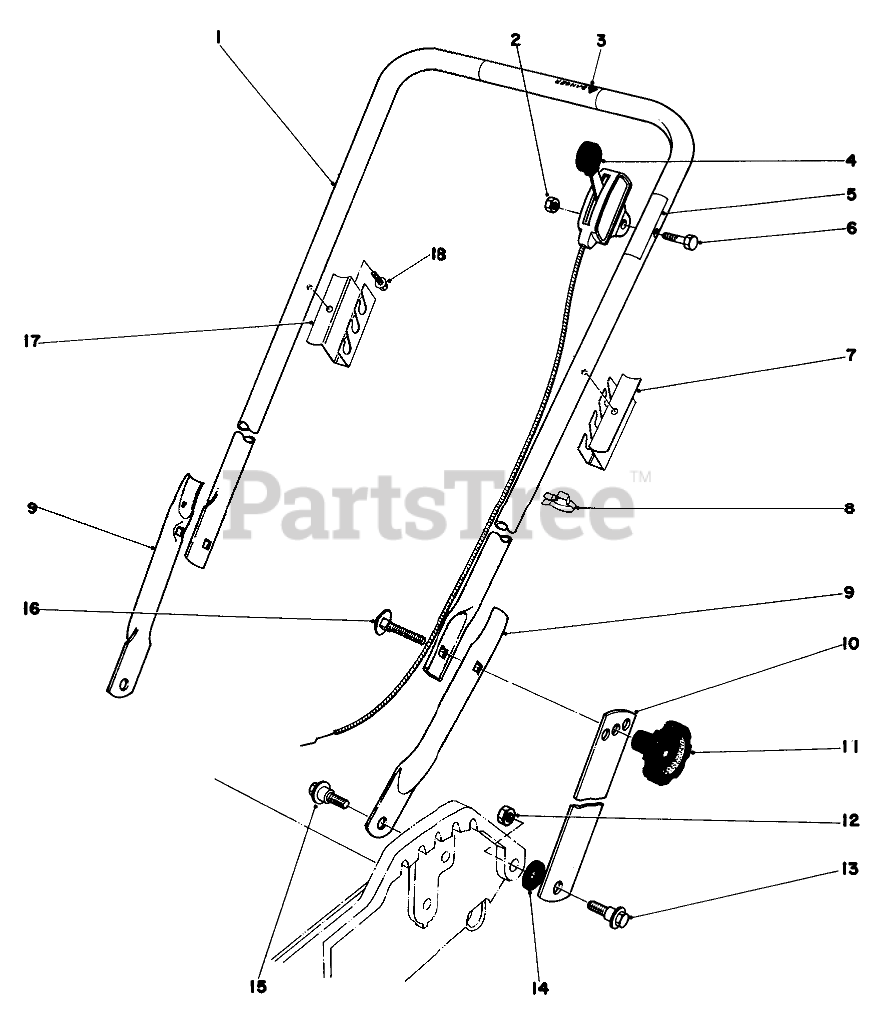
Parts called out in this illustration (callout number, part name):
1	Handle-Upper
2	NUT-LOCK
3	Decal
4	Throttle Control
5	Decal-Throttle
6	SCREW-HH
7	SUPPORT BAG LH
8	BOWDEN CLIP
9	Hand-Lower
10	18" HANDLE LATCH
12	Nut
13	SCREW-SHOULDER
14	SPACER
15	SCREW-SHOULDER
16	SCREW-HANDLE
17	SUPPORT BAG RH
18	SCREW-HWHTF
